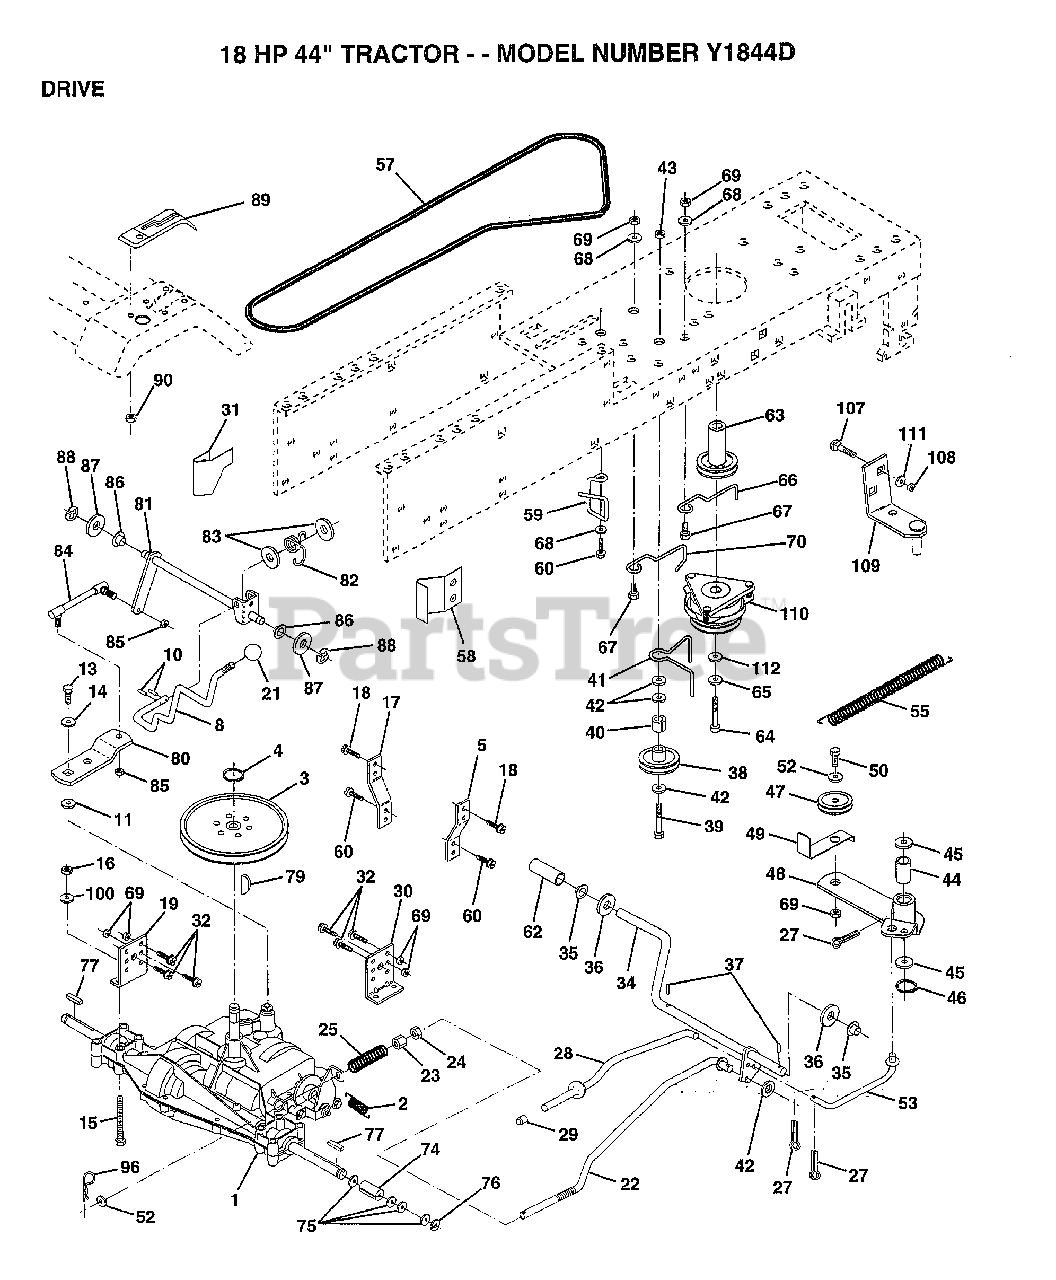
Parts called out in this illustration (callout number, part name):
1	TRANSAX. PRLES.
3	PULLEY TRANSAXLE
4	RING
5	STRAP TORQUE
10	PIN COTTER 1/8
11	WASH-SHFT PLT LT
14	WASHER PM
15	BOLT HEX
16	NUT
17	STRAP TORQUE
18	SCREW
19	BRKT TRANS LH
21	KNOB T (1/2-HOLE)
22	ROD BRAKE
23	NUT
24	NUT
25	"SPRING,ROD BRAKE"
27	COTTER PIN
28	BRAKE PARK ROD
29	PLUNGER CAP T
30	BRKT TRANS RH
31	KEEPER BELT LH
35	NYLON BEARING
36	WASHER LT
38	PULLEY.IDLER.FLAT
39	BOLT
40	SPACER T
41	BELT KEEPER LT
42	WASHER
43	NUT
44	"LY, BEARING"
45	WASHER LT
46	KLIP RING
48	ARM IDLER
49	RETAIN BELT
52	WASHER
53	"LINK, CLUTCH T"
55	"SPRING, RETURN LT"
57	BELT.GRDRV.94.75
58	"KEEPER,BELT RH"
59	KEEPER BELT CNTSP
60	SCREW
62	PEDAL COVER T
63	PULLEY ENGINE
65	LOCKWASHER
66	KEEPER BELT ENGLH
67	BOLT
68	WASHER
70	"KEEPER,BLT ENG LT"
74	SPACER HYT
75	WASHER
76	E RING HYT
77	SQ KEY STD
80	"ARM,SHIFT"
81	"SHAFT,SHIFTER"
82	"SPRING,TORSION"
83	WASHER
84	"ROD,TIE "
85	NUT 1/4-28
86	BUSHING
87	WASHER D
88	KLIP RING
89	CONSOLE SHIFTER
90	NUT
96	RETAINER M
100	WASHER M
107	BOLT
109	BRACKET.ASM.MTG
111	WASHER T
112	WASHER
